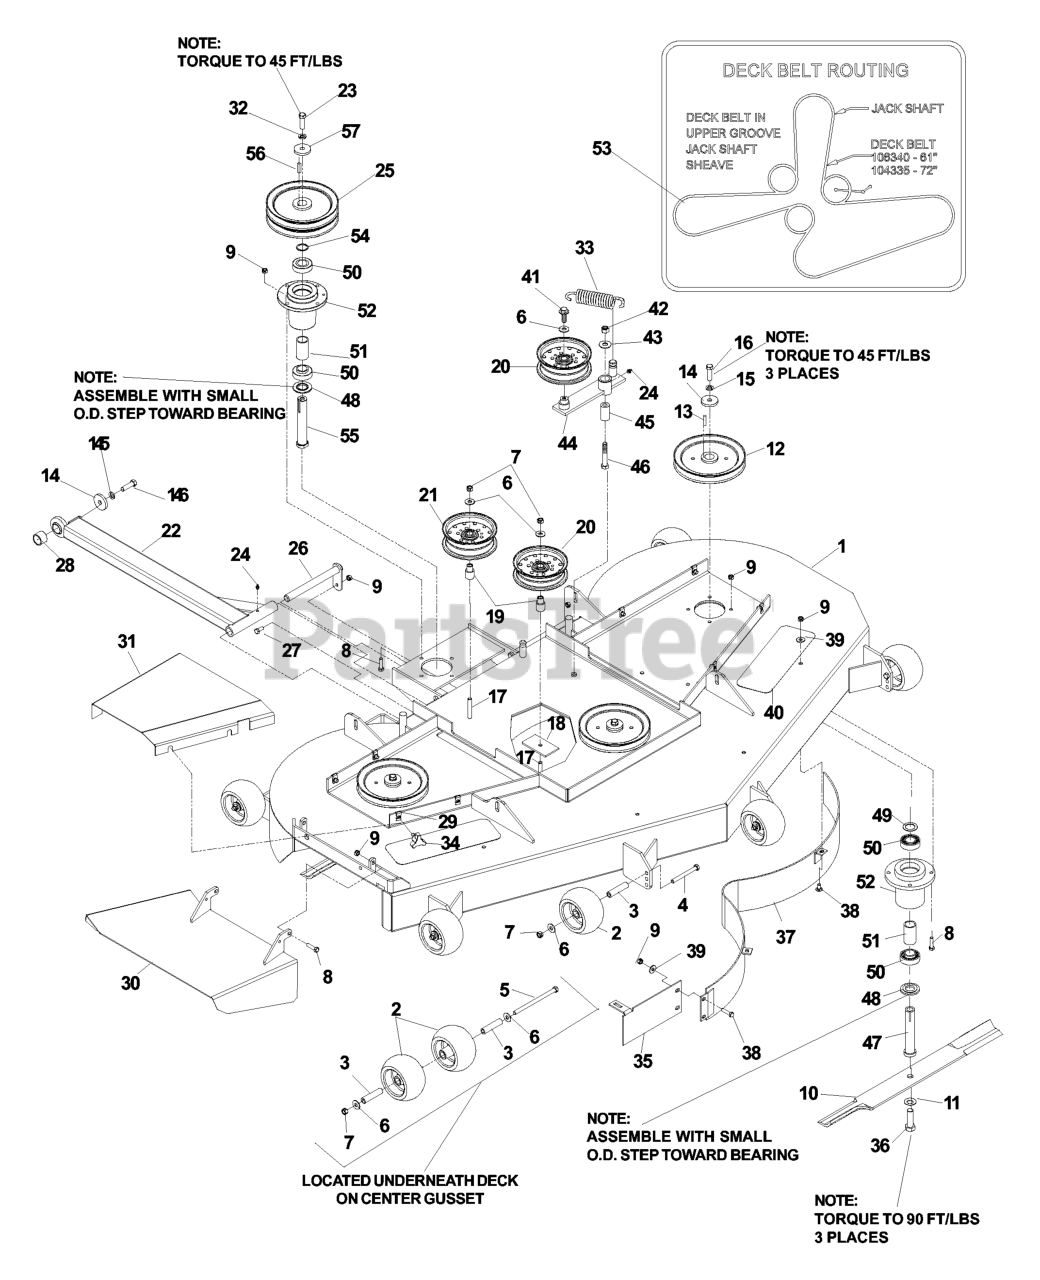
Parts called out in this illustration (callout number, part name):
1	DECK W/DECALS 72" HUS
2	ANTI-SCALP ROLLER
4	HCS 3/8C X 3 1/2
5	BOLT 3/8 X 6" GRD 8
6	WASHER 3/8 FLAT
7	NUT 3/8C CENTERBLOCK
8	HCS 5/16C X 1 1/4
9	NUT 5/16C CENTERLOCK
10	BLADE OEM - 25"
11	BELLEVILLE SPRING WASHER
13	KEY 1/4 SQ X 1 1/8
14	SPINDLE WASHER
15	WASHER 7/16 LOCK
16	HCS 7/16F X 1 1/2
17	HCS 3/8C X 3
18	SUPPORT PLATE
19	IDLER BUSHING
20	IDLER PULLEY
21	IDLER PULLEY (TALL)
22	STRUT WELDMT - R.H
22	STRUT WELDMT, L.H.
23	HCS 7/16F X 1 1/2
24	ZERK
25	SHEAVE WSL
26	PIN WELDMENT
27	HCS 5/16C X 3/4
28	SPACER, STRUT
29	U-CLIP 5/16-18 NUT RETAINER
30	DISCHARGE CHUTE
31	BELT SHIELD RH ORANGE
32	WASHER 7/16 LOCK
33	DECK SPRING
34	KNOB W/STUD
35	BAFFLE/CENTER-FLAT BLK
36	HEX SCREW-5/8F X 2 GR8
37	BAFFLE/CENTER-CURVED
38	CARRIAGE BOLT 5/16C X 5/8"
39	WASHER 5/16 FLAT
40	ANTI-SKID PAD
41	4CS 3/8C X 1 SERRATED HEAD
42	NUT 1/2-13 HEX NYLOC ZD
43	WASHER 1/2 FLAT
45	PIVOT BUSHING
46	HCS 1/2C X 3 1/4
47	SPINDLE SHAFT
48	COMBO SPACER
49	BUSHING.MACHINE.18.GAUGE
50	BEARING
52	HOUSING, DIE CAST
53	BELT, DECK
54	BUSHING.MACHINE.18.GAUGE
55	SPINDLE SHAFT
56	KEY 1/4 SQ X 1 1/8
57	SPINDLE WASHER
